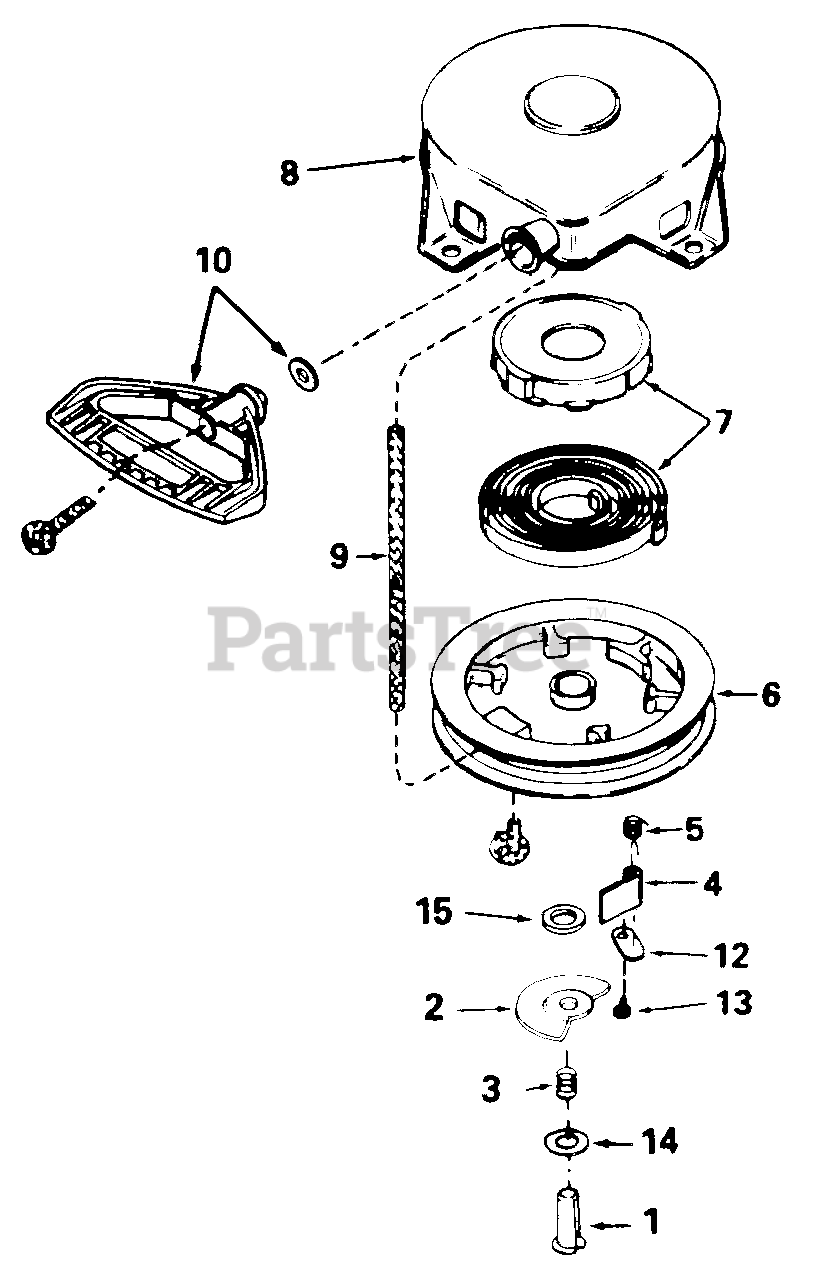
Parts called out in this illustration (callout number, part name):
1	Pin, Spring
3	Spring, Brake
4	Dog, Starter
5	Spring, Dog
7	Spring & Keeper Ass'y.
8	Housing, Starter
9	Rope, Starter
10	Handle, Mitten Grip (Not Included With Starter)
12	Retainer, Dog
13	Screw, No. 6 x 5/16
